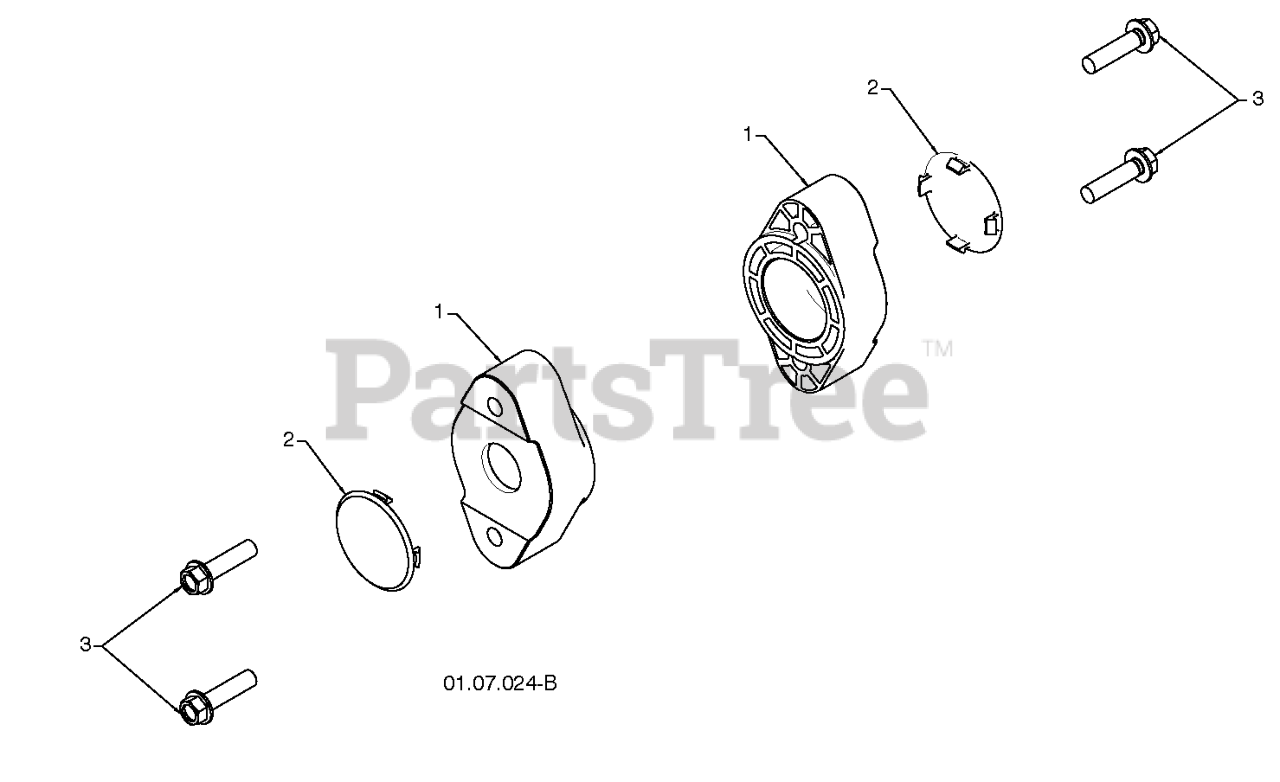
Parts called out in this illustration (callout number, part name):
1	BEARING.AUGER.SHAFT
2	PLUG.BEARING.HOLE.HSG
3	SCREW, HEX HD 5/16X1
